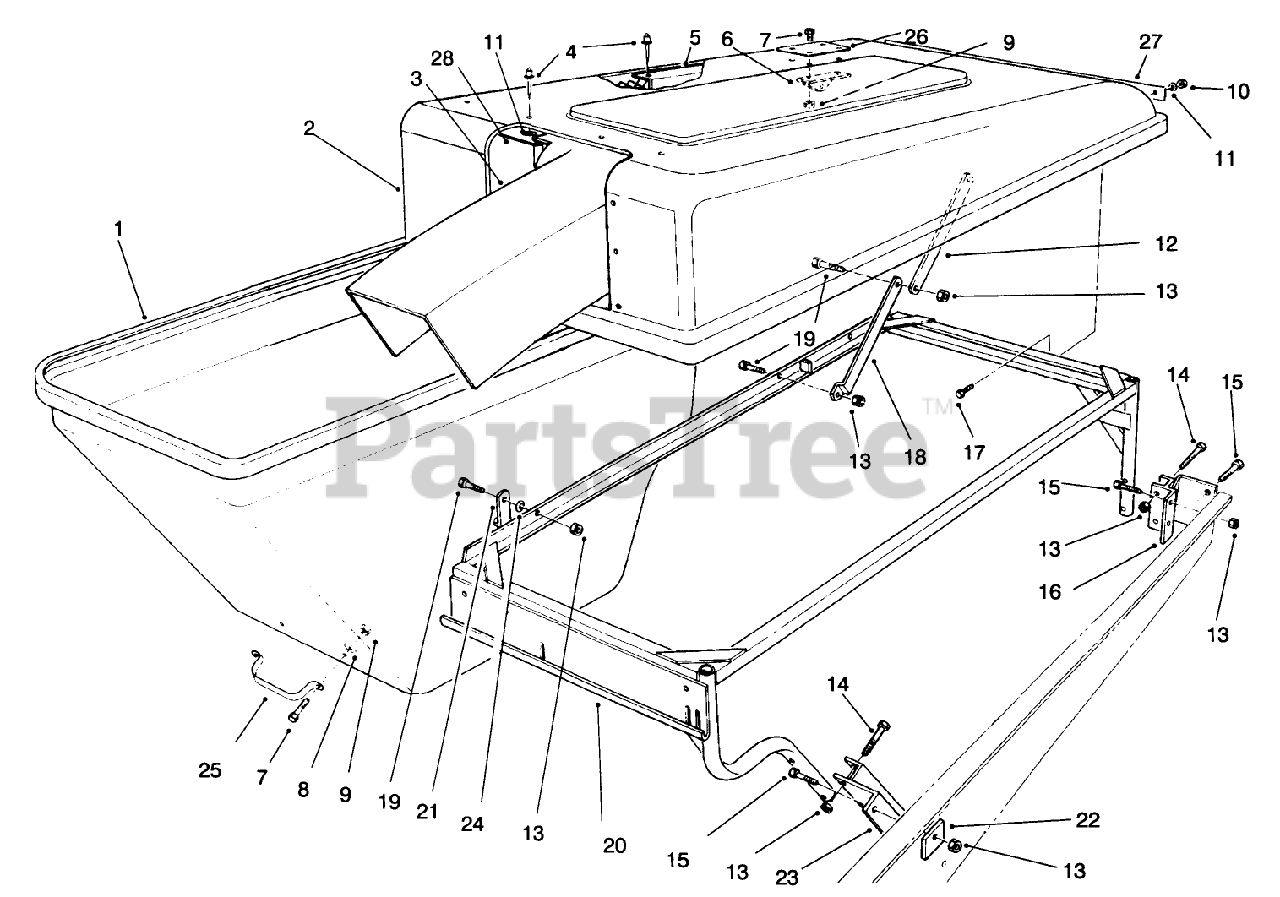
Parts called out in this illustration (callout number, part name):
1	BAGGER HOPPER
2	BAGGER HOOD
3	BAGGER SNOUT
4	NUT-LOCK
5	Bagger Screen
6	Pivot
7	SCREW-HH
8	WASHER-FLAT
9	NUT-LOCK, NI
10	NUT-LOCK, NI
11	WASHER-FLAT
12	Link
13	NUT-LOCK, NI
14	SCREW-HH
15	SCREW-HH
16	Bracket-Rear
18	Link-Bag
19	SCREW-HH
20	HOPPER FRAME WA
21	Latch-Hopper
22	Plate-Reinforcing
23	Bracket-Front
24	WASHER-SPRING
25	Handle
26	HOOD PLATE
27	HINGE PLATE
28	Baffle
